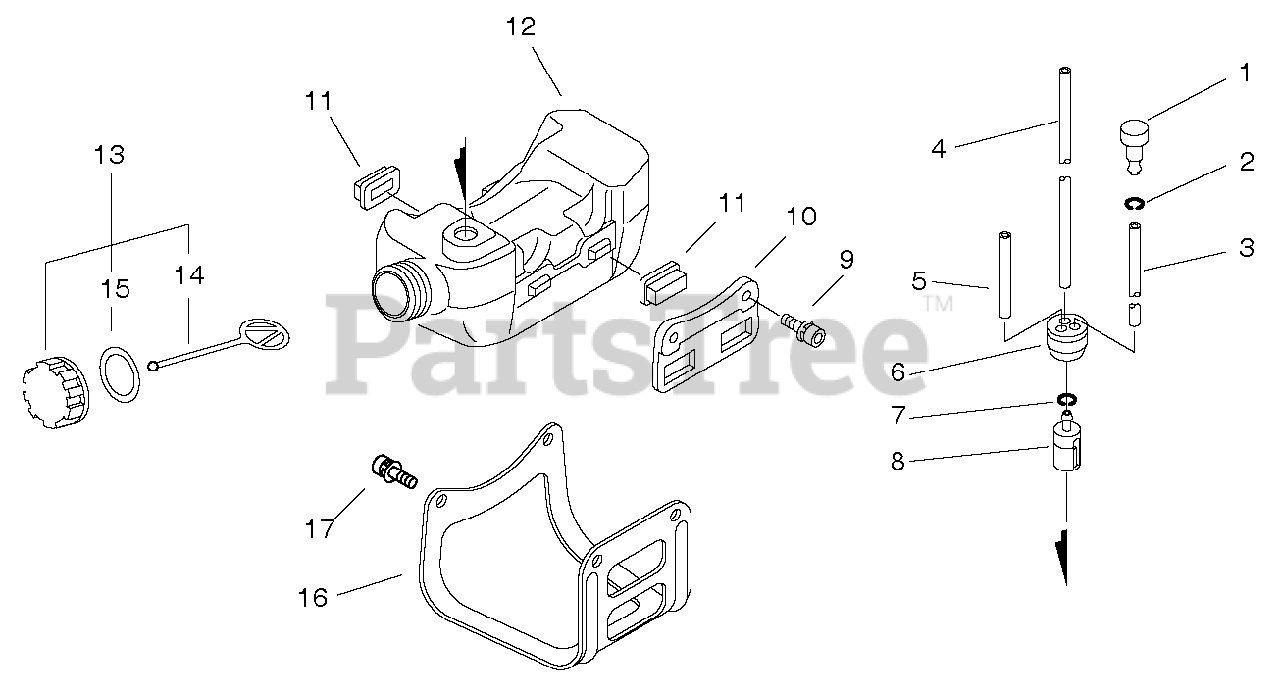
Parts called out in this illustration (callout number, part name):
1	VENT ASSY
3	PIPE, FUEL 3×5×90 BLACK
4	PIPE, FUEL 3x-5x-180
5	PIPE, FUEL RETURN 3×6×90 MM CLEAR
6	GROMMET, FUEL Ø5
7	CLIP 6 MM
8	FILTER, FUEL
9	BOLT 5×20
10	BRACKET, FUEL TANK
11	CUSHION, FUEL TANK
12	TANK, FUEL
13	CAP ASSY, FUEL
14	CONNECTOR, CAP L= 100 MM
15	GASKET, FUEL CAP
17	BOLT 5×12
